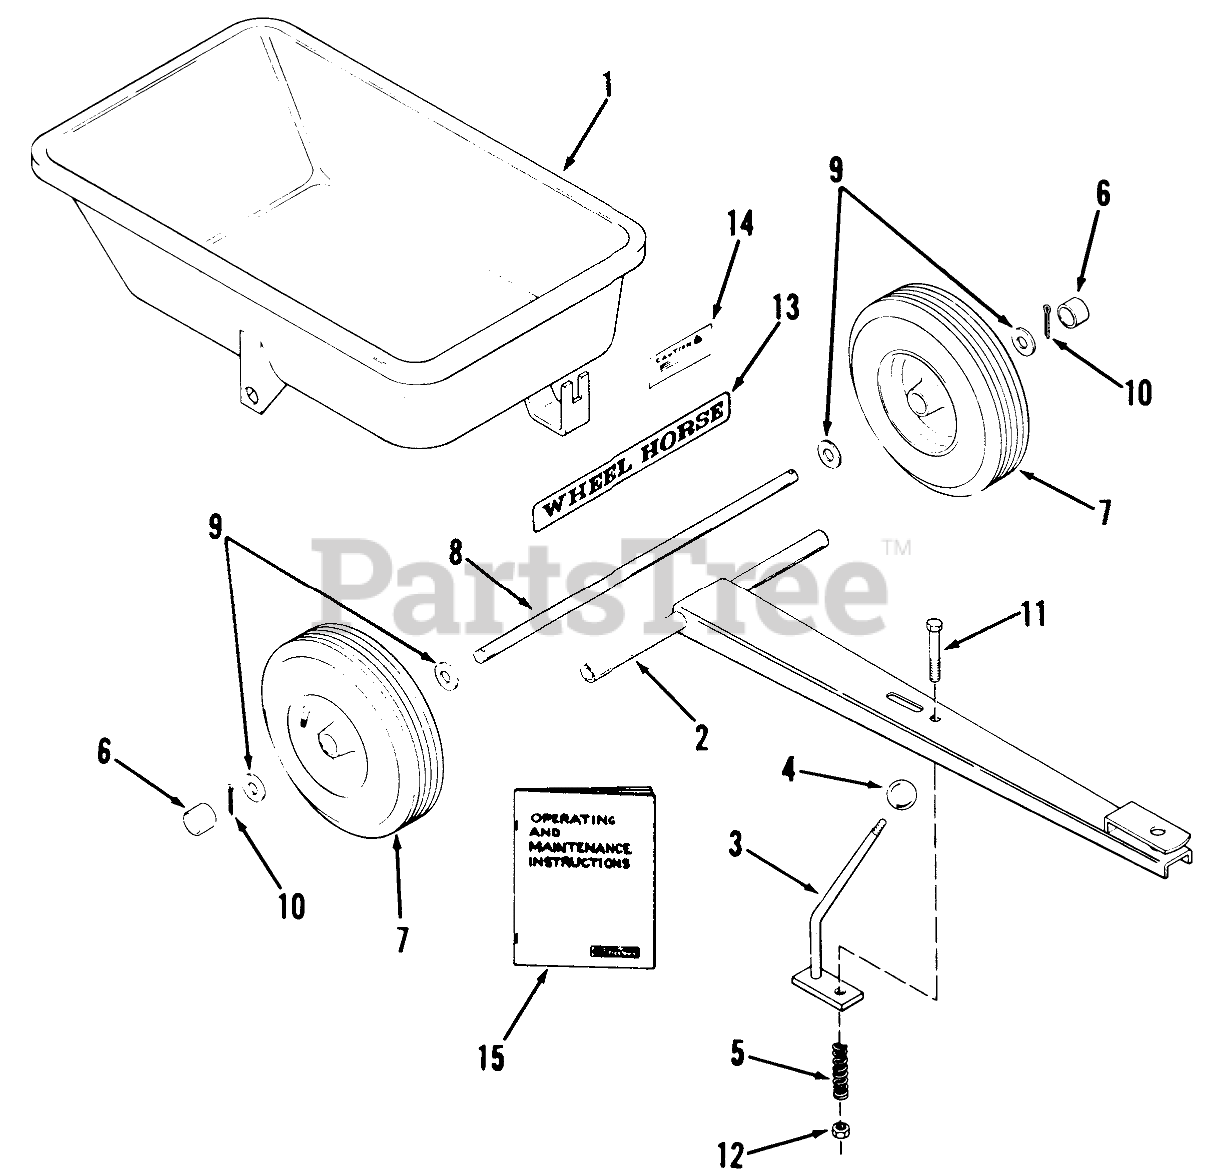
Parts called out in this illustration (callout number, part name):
1	Box Ass-y.
2	Frame Ass-y.
3	Latch Assembly
4	Knob
5	Spring
6	Hub Cap
7	Tire & Wheel
8	Axle
9	WASHER
10	Cotter Pin
11	HHCS
12	Nut
13	DECAL-WHEEL HORSE
14	Decal-Weight Limit
15	Operating and Maintenance Instructions
